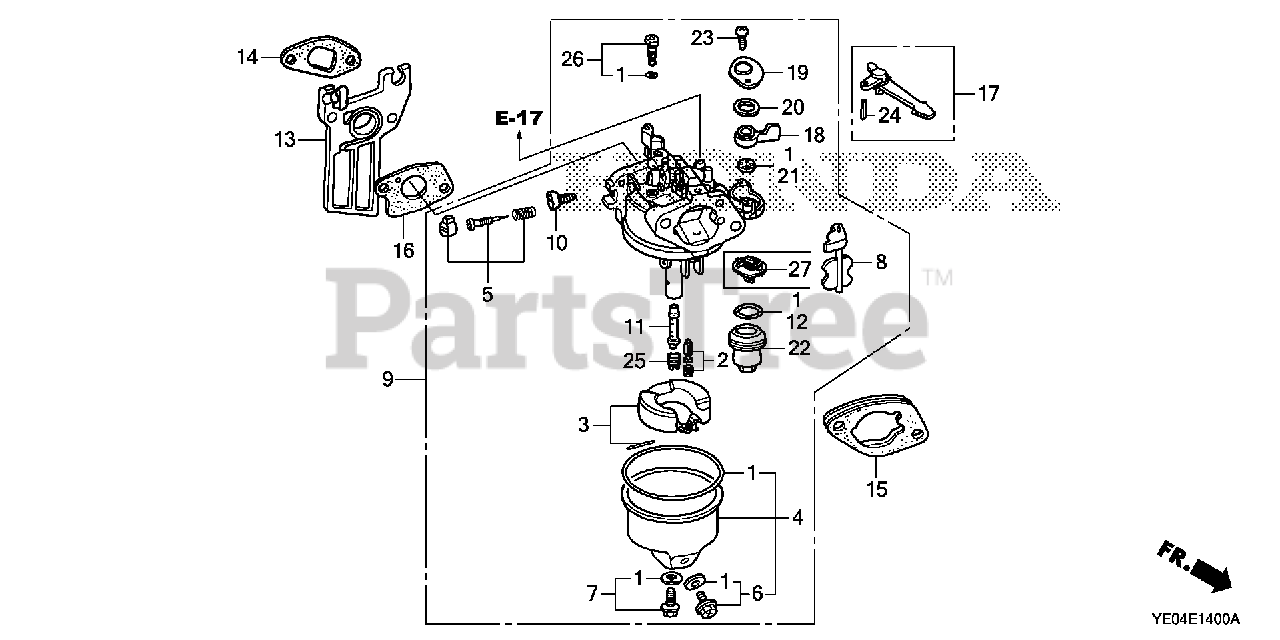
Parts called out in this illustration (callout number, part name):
1	GASKET SET
2	VALVE SET, FLOAT (SEAT NOT INCLUDED)
4	CHAMBER SET, FLOAT
5	SCREW SET, PILOT
6	SCREW SET, DRAIN
7	SCREW SET
9	CARBURETOR ASSY. (BE65Q A)
10	SCREW, THROTTLE STOP
11	NOZZLE, MAIN
12	GASKET, FUEL STRAINER CUP
13	INSULATOR, CARBURETOR
14	GASKET, INSULATOR
15	SPACER, CARBURETOR
16	GASKET, CARBURETOR
17	LEVER, CHOKE (STD)
18	LEVER, PETCOCK
19	PLATE, LEVER SETTING
20	SPRING, PETCOCK LEVER
21	GASKET, PETCOCK
22	CUP, FUEL STRAINER
23	SCREW, PAN (3X6)
24	PIN, SPRING (2X12)
25	JET, MAIN (#68)
25	JET, MAIN (#70)
25	JET, MAIN (#65)
26	JET SET, PILOT (#35)
